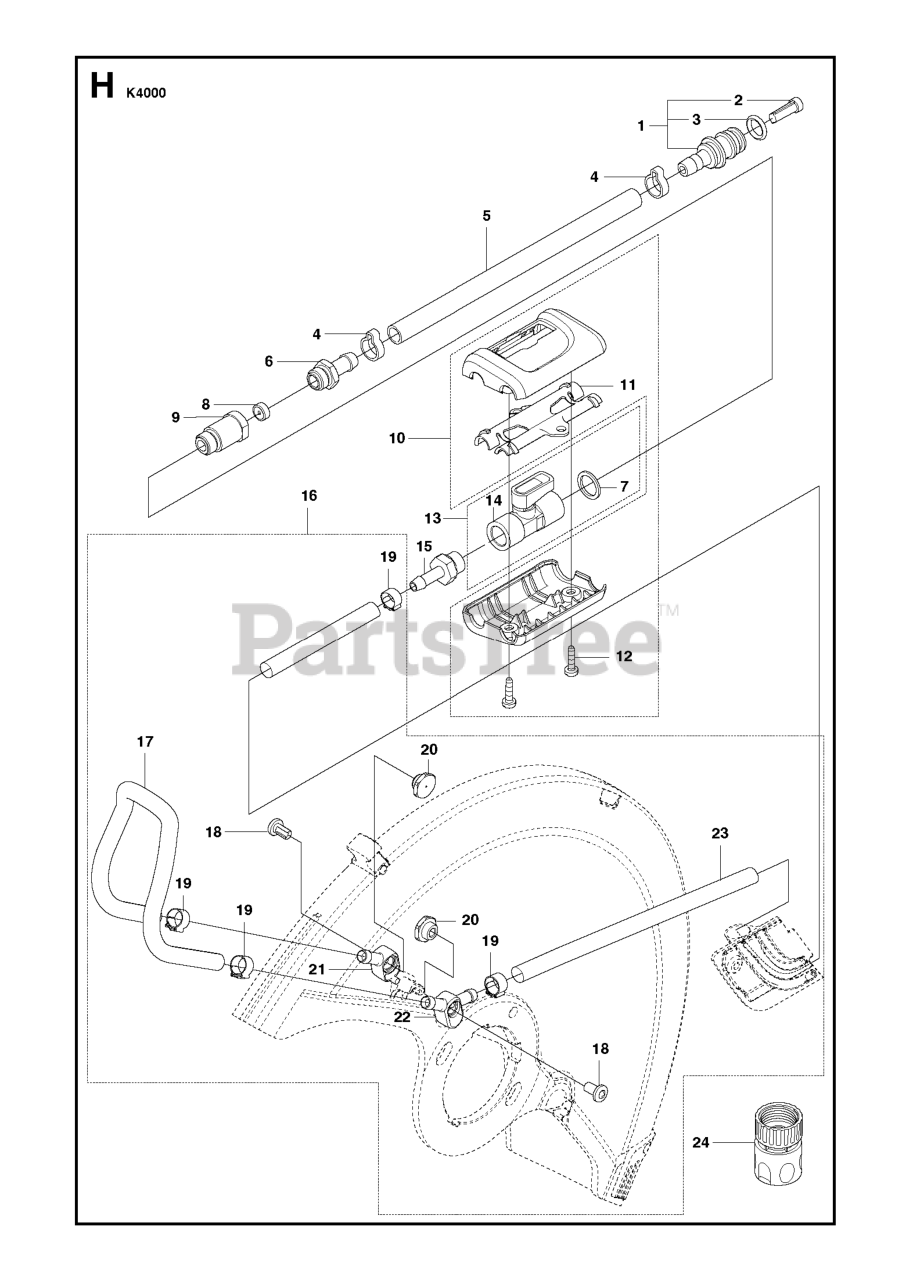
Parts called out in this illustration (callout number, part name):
1	NIPPLE
4	HOSE CLAMP
8	FLOW CONTROL
9	NIPPLE G 1/4"
10	SPARE PARTS KIT
11	INSERT VALVE HOUSING K3000 WET
12	SCREW
13	VALVE KIT
19	HOSE CLAMP
24	FEMALE QUICK COUPLER
24	COUPLER, 1/2" HOSE W/STOP ORIG
